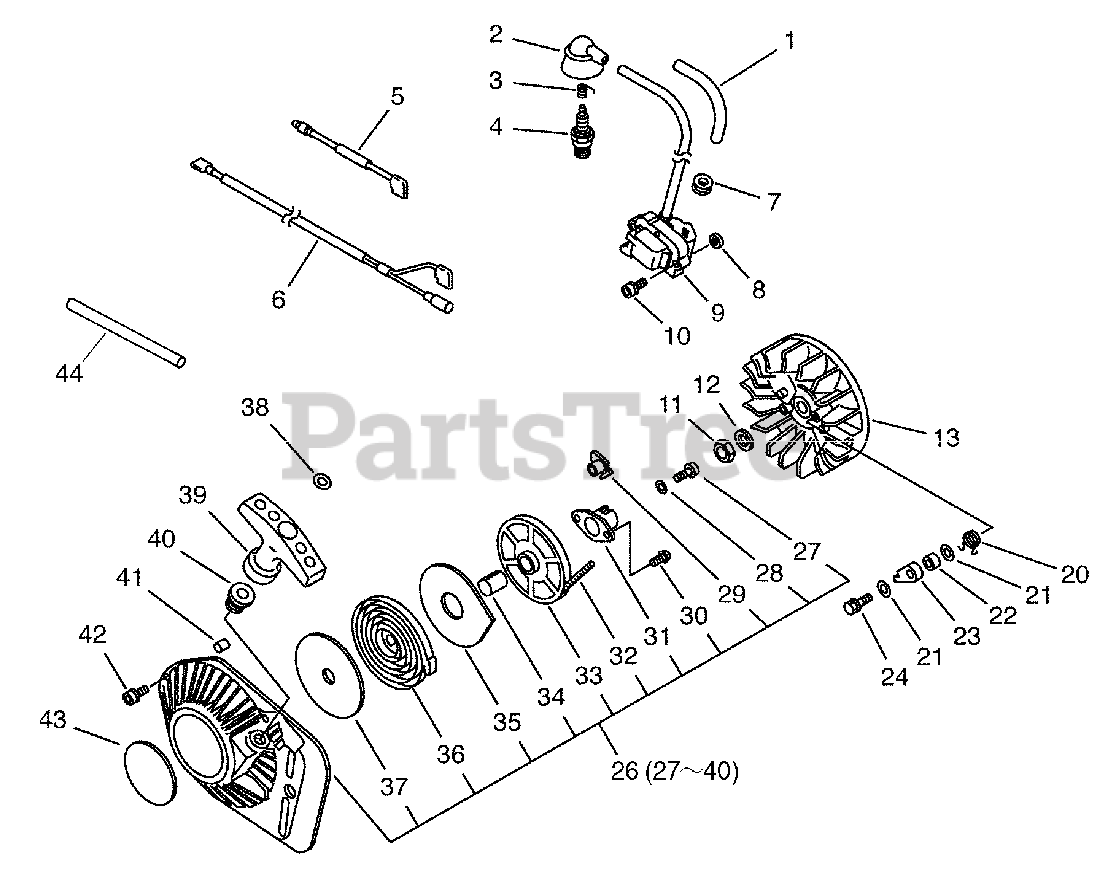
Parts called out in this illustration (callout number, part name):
1	TUBE, PROTECTIVE
2	CAP, SPARK PLUG
3	TERMINAL, SPARK PLUG CAP
4	SPARK PLUG -- BPM-7A
5	LEAD - IGNITION
6	LEAD - GROUND
9	COIL, IGNITION
10	SCREW - 5X25
13	FLYWHEEL
20	SPRING, RETURN
21	WASHER - 6
23	PAWL, STARTER
24	BOLT - 6X16
26	STARTER ASSY
27	SCREW - 5X14
29	RETAINER, ROPE
30	SCREW - 4X12
31	CATCHER, PAWL
32	ROPE, STARTER
33	REEL, ROPE
35	PLATE, STARTER
36	SPRING, REWIND
37	PLATE, STARTER
38	WASHER - 5
39	GRIP, STARTER
40	GUIDE, ROPE
41	PIN - LOCATING
42	SCREW - 6X25
43	LABEL - ECHO
